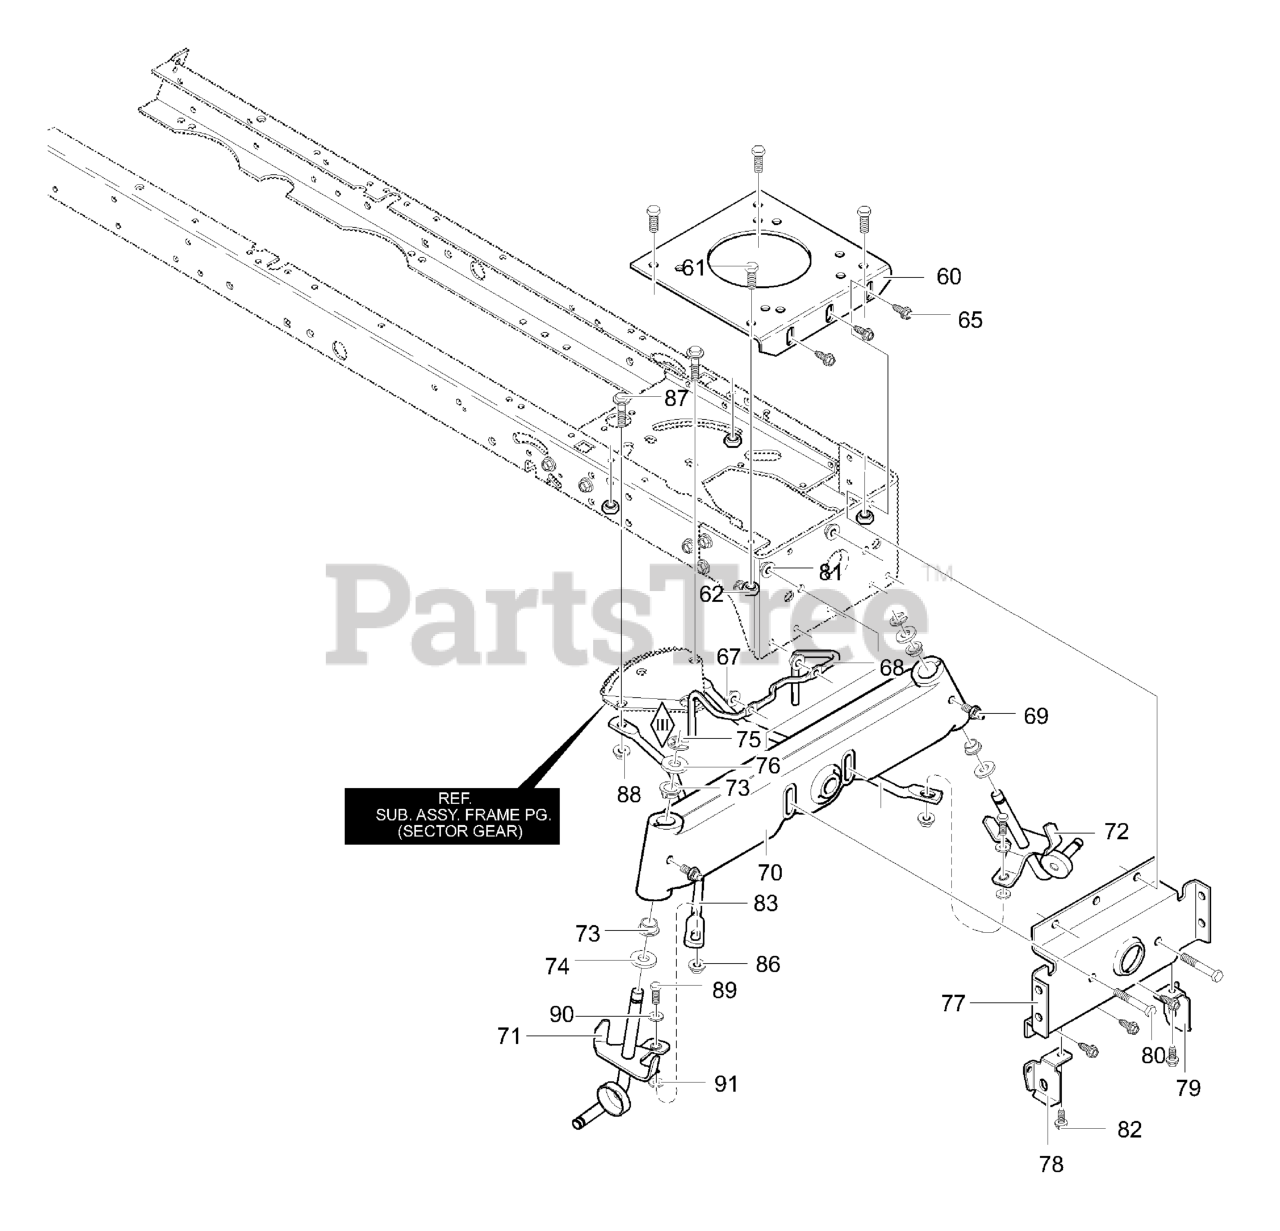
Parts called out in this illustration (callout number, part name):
60	Engine Plate
61	Screw, .312-18x.75
62	Nut, 5/16-18
65	Screw, .312-18x.75
67	Nut, 5/16-18
68	Guide-Stack Pulley Belt
69	Zerk, Grease
70	Axle, Cast Machined
71	Spindle, Long RH
72	Spindle, Long LH
73	Bearing, Spindle
74	Washer, .766IDx1.62ID
76	Washer, Flat
77	Hanger, Axle
78	Hanger, Deck RH
79	Hanger, Deck LH
80	Screw, 5/16-18 x 3.00
81	Nut, 5/16-18
82	Screw, .312-18x.75
83	Drag Link, LH
84	Drag Link, RH
86	Nut, 3/8-16
87	Shoulder Bolt
88	Nut, 3/8-16
89	Screw, 3/8-16 x 1.50
90	Flatwasher
91	Flatwasher
